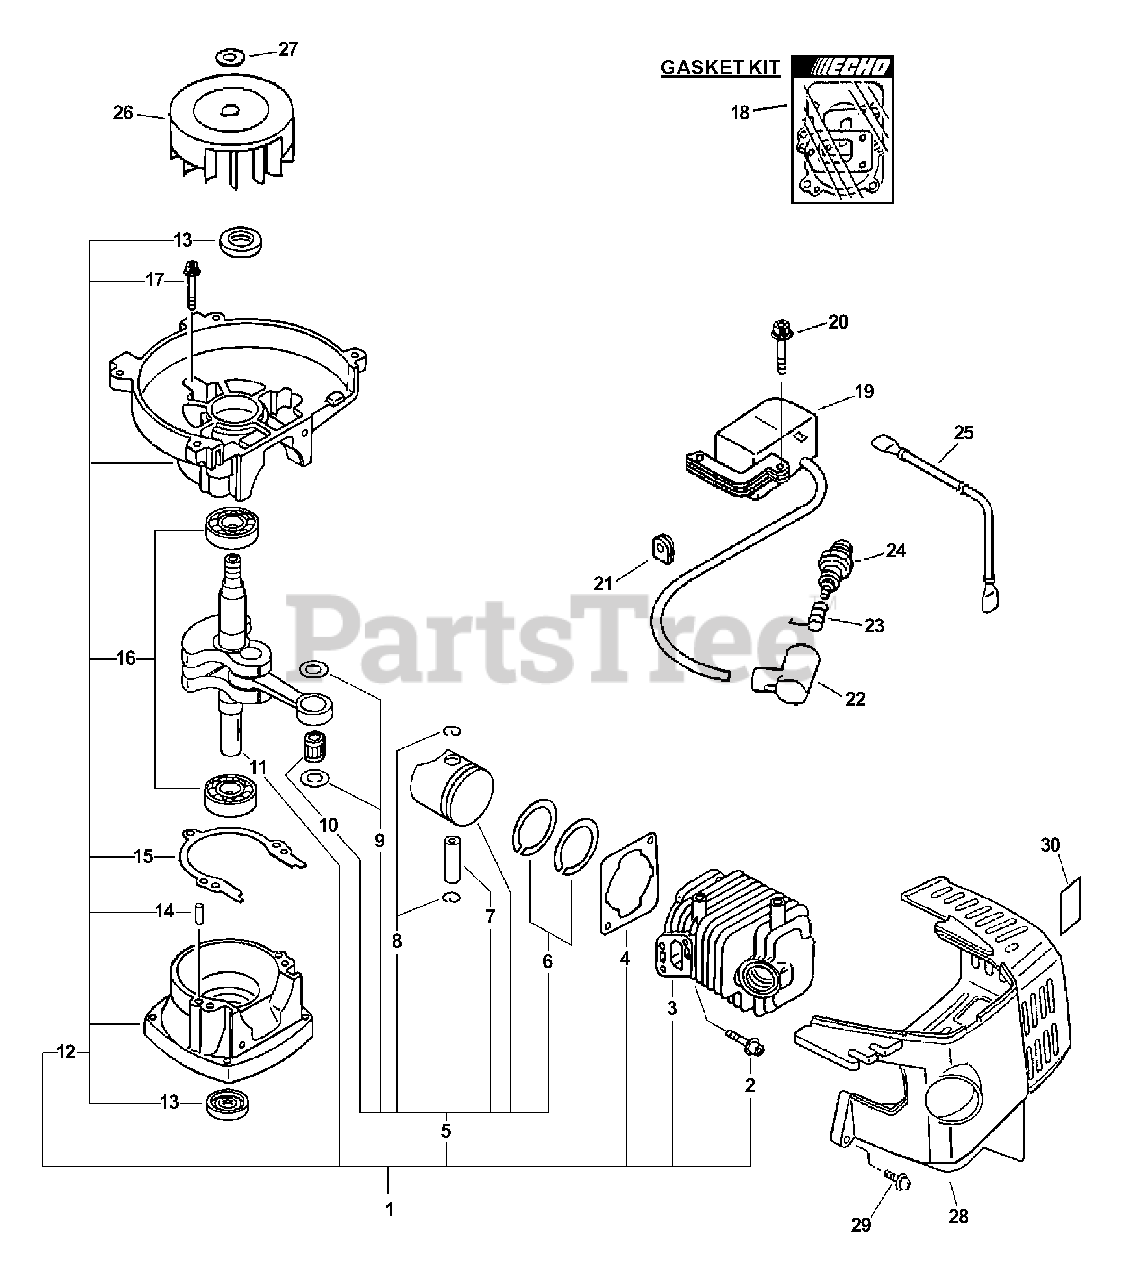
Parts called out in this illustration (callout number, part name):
1	SHORT BLOCK -- SB1051
2	SCREW - 5X22
3	CYLINDER
4	GASKET, CYLINDER
5	PISTON KIT
6	RING, PISTON
7	PIN, PISTON
8	RING, RETAINING
10	BEARING, NEEDLE - 8
11	CRANKSHAFT ASSY
12	CRANKCASE KIT
13	SEAL, OIL
14	PIN - LOCATING
15	GASKET, CRANKCASE
16	BEARING, BALL - 6201
17	SCREW - 5X28
18	GASKET KIT
19	COIL, IGNITION
20	SCREW - 4X22
22	CAP, SPARK PLUG
23	TERMINAL, SPARK PLUG CAP
24	SPARK PLUG -- BPM-7Y
25	LEAD - IGNITION
26	FLYWHEEL
27	WASHER - 8
28	COVER, ENGINE
29	SCREW - 4X22
30	LABEL - HOT SURFACE
